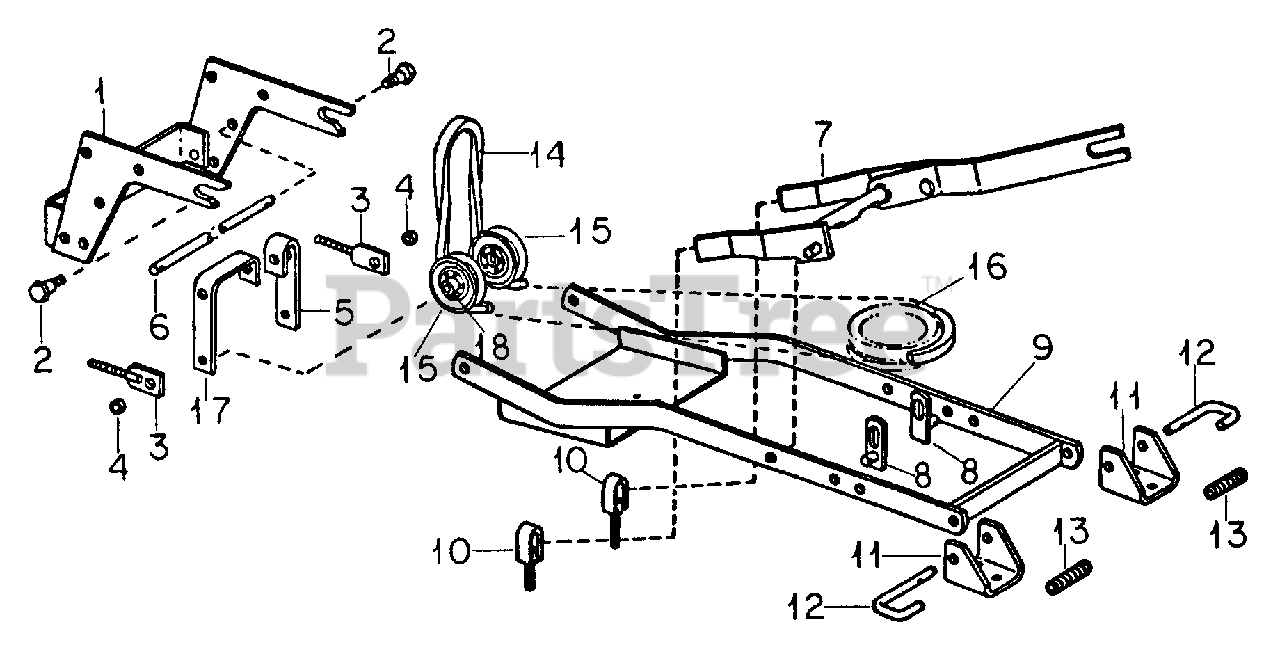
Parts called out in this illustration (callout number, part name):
1	HANGER ASSY, FRONT
2	BOLT, SHOULDER
3	BRACKET ASSY, IDLER ADJ
4	SPACER, IDLER ADJ
5	SUPPORT, IDLER RH
6	ROD, FRONT MOUNTING
7	SUPPORT ASSY, FRONT PIVOT LINK
8	LINK ASSY, LIFT
9	ARM ASSY, FRAME SIDE
10	LINK ASSY, MOWER SUPPORT
11	BRACKET, MOWER SUPPORT
12	PIN, MOWER SUPPORT
13	SPRING, MOWER SUPPORT PIN
14	BELT, MULE DRIVE 3/8 X 80
14	BELT, MULE DRIVE 3/8 X 75 1/2 SL
15	PULLEY, DRIVE BELT IDLER
16	PULLEY, CENTER
17	SUPPORT, IDLER LH
18	BEARING ASSY, IDLER PULLEY
